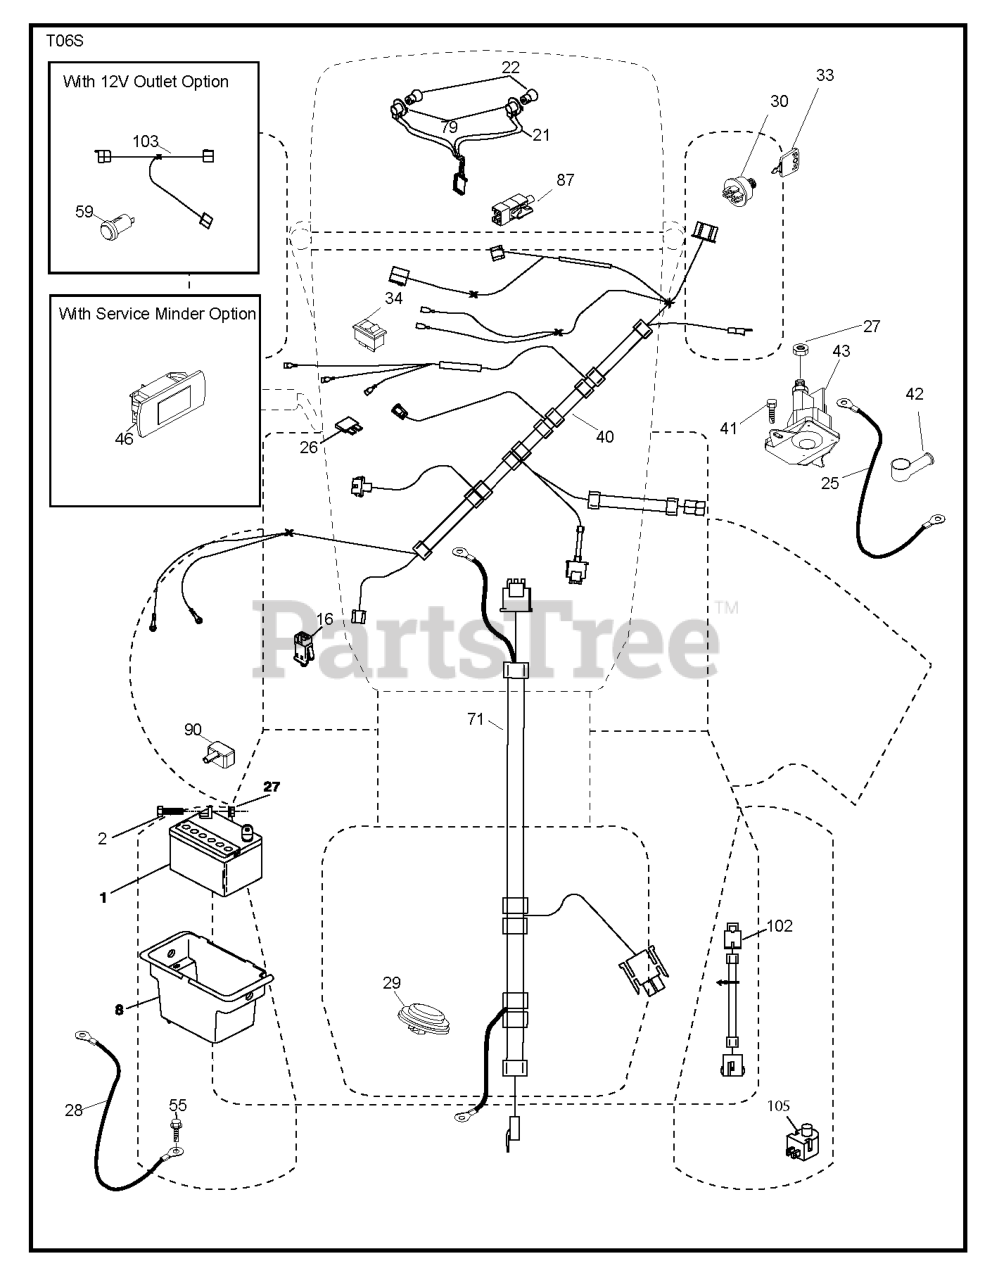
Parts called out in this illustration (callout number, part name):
1	Battery 12 Volt 25 Amp
2	BOLT.HEX.1/4.X.3/4.DICHROMATE
8	BOX.BATTERY.MNT.REAR.L
16	SWITCH INTERLOOK PUSH-IN
21	HARNESS.LIGHT W/4152J BULBS
25	CABLE.STARTER.6G.BL/RED.17.5
26	FUSE 20AMP
27	NUT
28	CABLE.BLACK.18"REAR.BA
29	SWITCH.SEAT.DELTA.OPC.
30	SWITCH.IGN.DELTA.W.LGH.ROS
33	KEY.CHAIN.BLISTER.PACK.GEN.INT
40	HARNESS IGN. DASH
41	SCREW
42	TERMINAL COVER
43	SOLENOID.W/BRASS.PLUNGER
46	RP.GUAGE.SRVCMNDR.HRMTR.
55	SCREW 5/16"
71	HARNESS.IGN.CHASS.TEX.REAR.BAT
79	BULB HOLDER ASM.
87	SWITCH.INTRLCK.CLUTCH.
90	COVER.TERMINAL.BATTERY
102	HARNESS PIGTAIL PCH TEX ROS
105	REVERSE SWITCH
